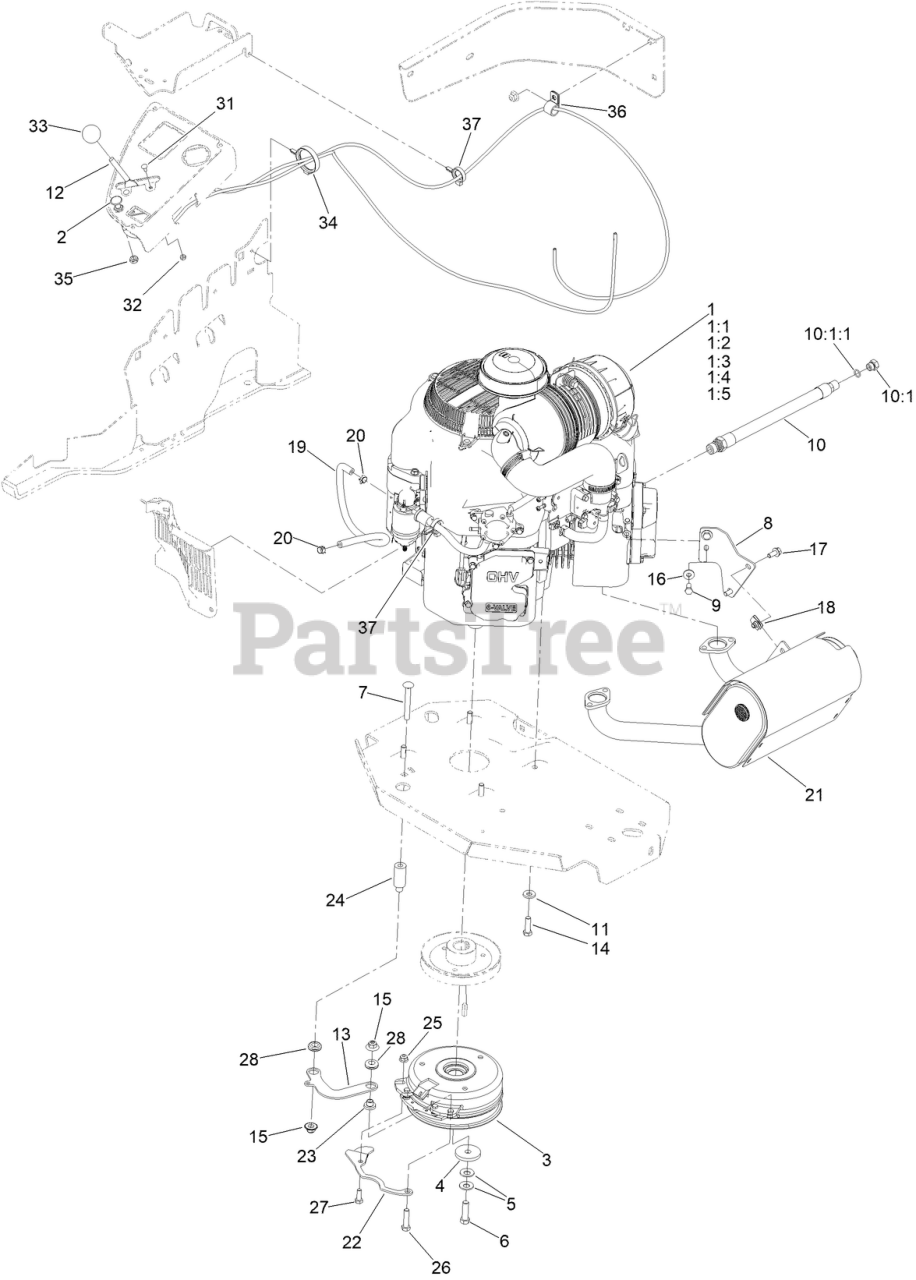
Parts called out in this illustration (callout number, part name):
1:1	FILTER-OIL KAW
1:2	ELEMENT-FILTER, AIR (OUTER)
1:3	ELEMENT-FILTER, AIR (INNER)
1:4	Filter-Fuel
1:5	Spark Plug
2	CABLE-CHOKE
3	CLUTCH KIT
4	WASHER-CLUTCH
5	WASHER-SPRING
6	SCREW-HH, W/LOCTITE
7	SCREW-CARR
8	BRACKET-MUFFLER
9	SCREW-HH
10	ENGINE OIL DRAIN HOSE ASM
10:1	PLUG-HH
10:1:1	O-RING
11	WASHER-BELLEVILLE
12	THROTTLE-CONTROL
13	LINK-ANCHOR, CLUTCH
14	SCREW-HH
15	NUT-FLANGE, NI
16	WASHER-SPRING
17	SCREW-HHF
18	NUT-U
19	HOSE-FUEL
20	CLAMP-HOSE
21	MUFFLER
22	BELT-GUIDE
23	SPACER
24	SPACER
25	NUT-HF, NI
26	SCREW-HH
27	SCREW-HH
28	GROMMET-RUBBER
31	BOLT-CARR
32	NUT-LOCK, NI
33	KNOB-BALL
34	CLAMP-HARNESS
35	NUT-HJ
36	CLIP-LOOM
37	CLAMP-HOSE
